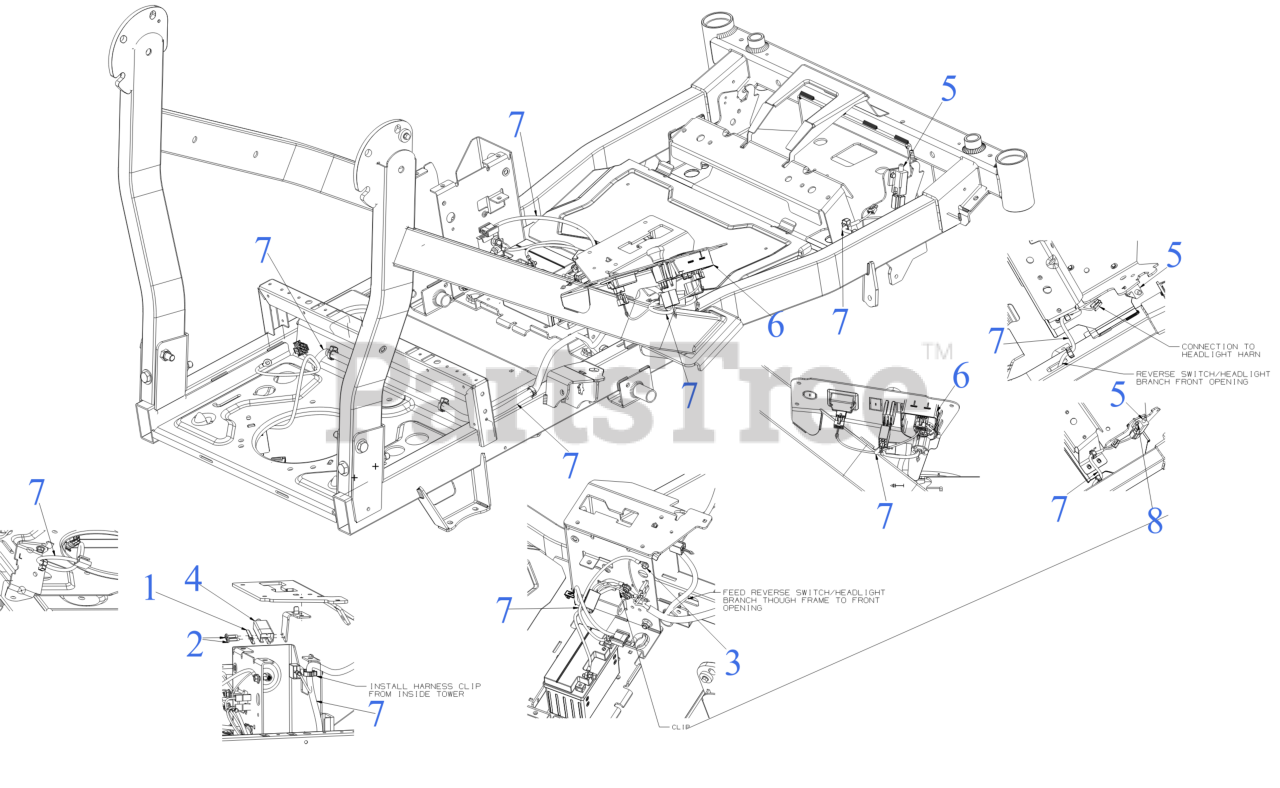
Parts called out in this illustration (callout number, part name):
1	PLATE-SWITCH
2	SCREW #10-24X11/16 T-25
3	SCREW 1/4-20X.625
4	SCREW MOUNT SWITCH NO/NC
5	INTERLOCK SWITCH (NO/NC)
6	IGNITION MODULE SWITCH (RMC ELC PTO WHTE)
7	MAIN HARNESS (KH-KT)
7	12V SOLENOID
8	SHOULDER SCREW
